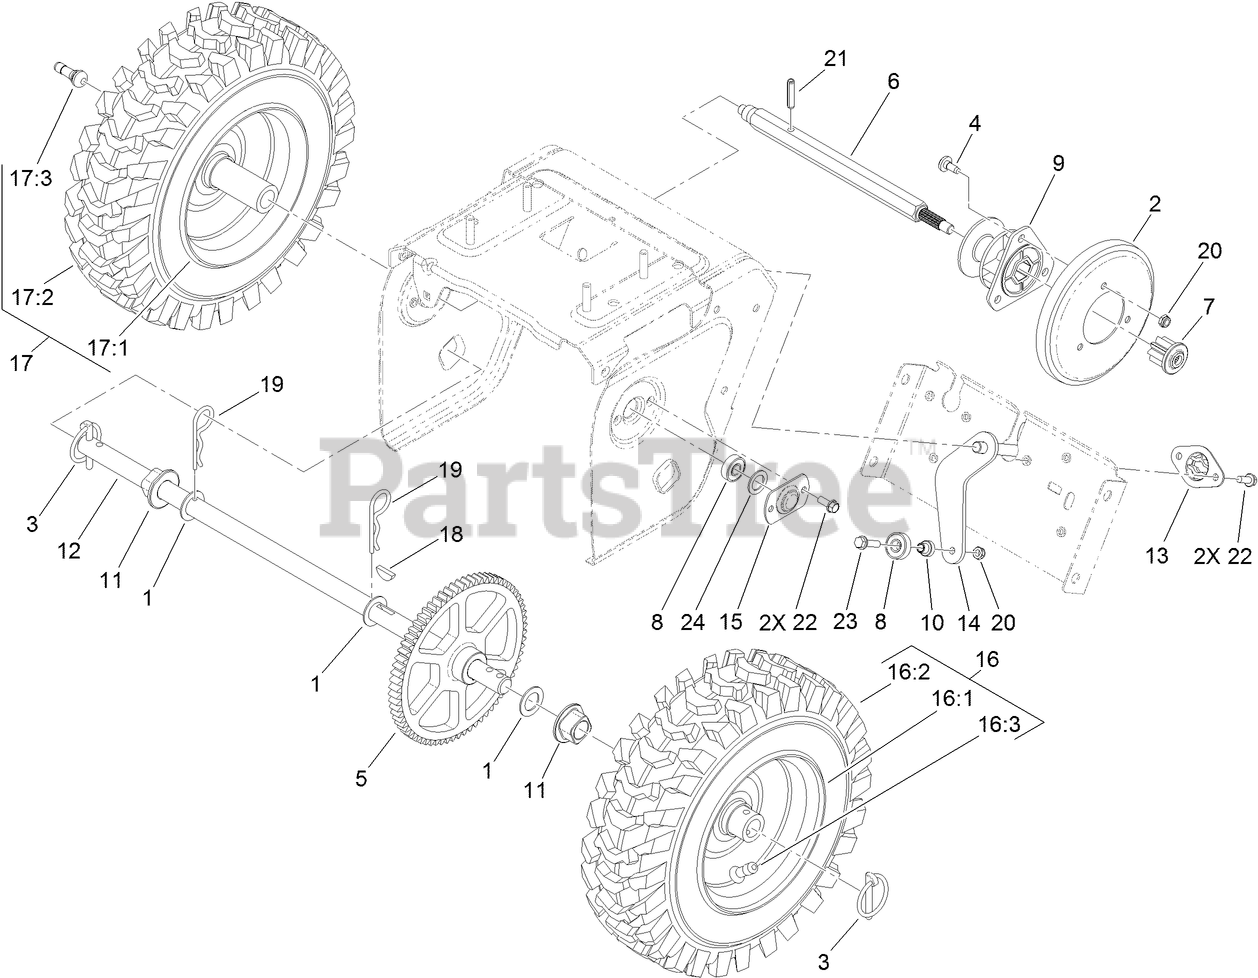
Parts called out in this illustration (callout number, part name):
1	WASHER-THRUST
2	WHEEL-FRICTION
3	KLIK PIN ASM
4	SCREW-SHOULDER
5	GEAR-AXLE
6	SHAFT-HEX
7	GEAR-PINION, 8 TOOTH
8	BEARING-BALL
9	TRUNNION
10	SPACER-PLATE, SHIFT
11	BUSHING-AXLE
13	RETAINER-PLATE, SHIFT
14	SHIFT PLATE ASM
16	Loose Parts Package
17	Loose Parts Package
18	KEY-WOODRUFF
19	PIN-HAIR
20	NUT-LOCK, NI
21	PIN-ROLL, SLOTTED
22	SCREW-HWH
23	SCREW-HWHTF
24	WASHER-RUBBER
